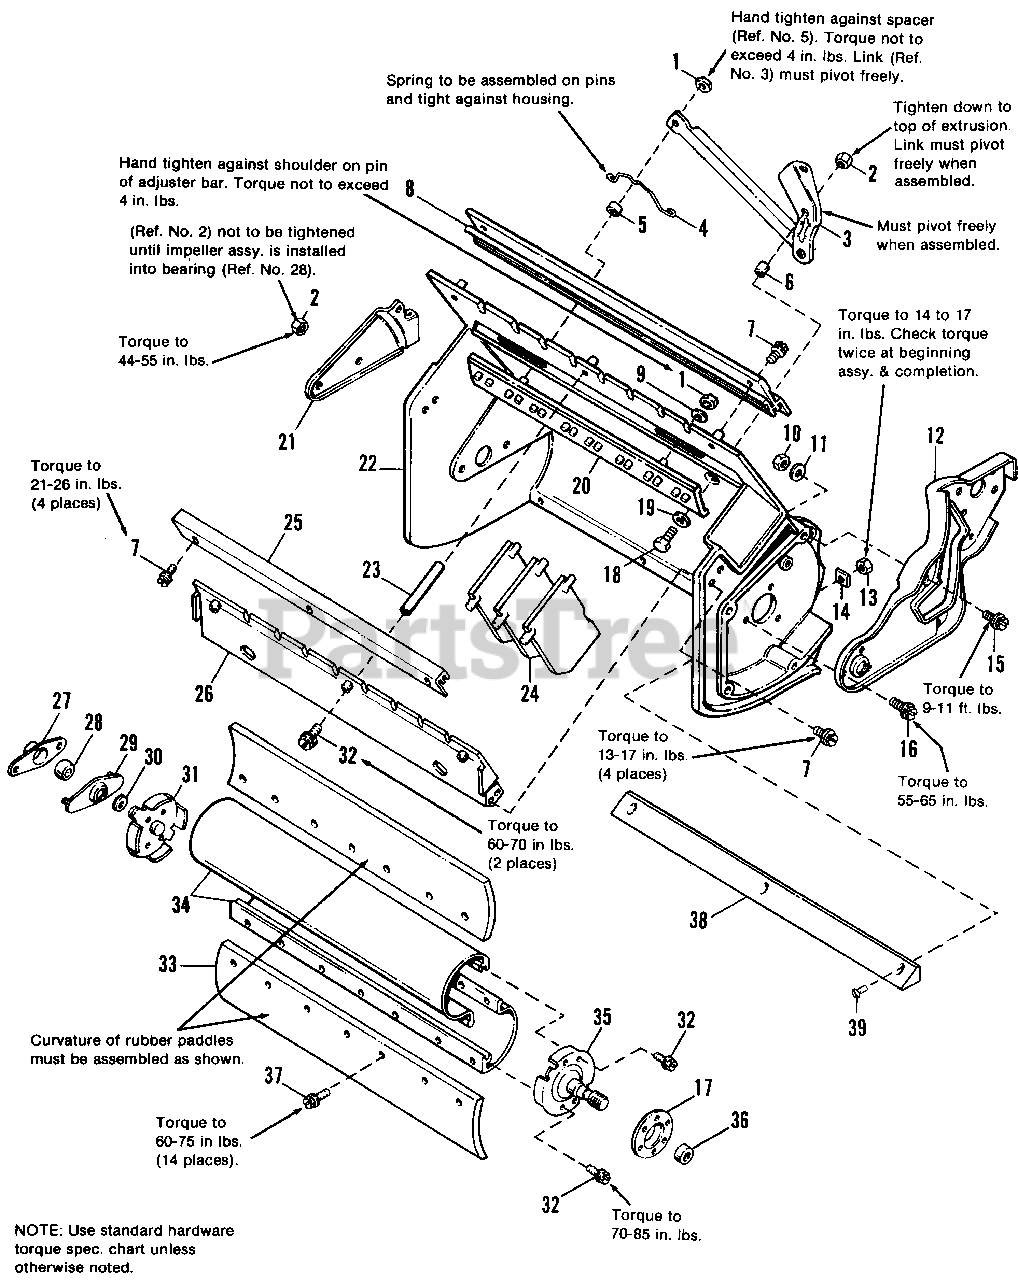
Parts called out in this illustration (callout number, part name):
1	NUT, Self-Threading
2	LOCKNUT, Hex, 1/4-20
3	VANE ASSY., Control
4	SPRING, Detent
7	SCREW, Hex, Wash. Hd., Slotted, #10-24 x 1/2
9	WASHER, Nylon
10	LOCKNUT, Hex, 5/16-18
11	WASHER, Plain, 5/16
13	NUT, Nylon Insert, #10-24
15	CAPSCREW, Hex Hd., 5/16-18 x 3/4
16	SCREW, Hex, Wash. Hd., #10-14 x 5/8
17	RETAINER, Bearing
18	CAPSCREW, Hex Hd., 1/4-20 x 1
19	WASHER, Plain, 1/4
20	BAR, Adjustment
21	BRACKET, R.H.
22	HOUSING, Impeller
26	MOUNT, Front
29	FLANGE ASSY.
30	WASHER, Plain, 5/8
31	FLANGE & SHAFT ASSY., R.H.
32	SCREW, Hex Wash. Hd., Slotted, #10-14 x 1
34	DRUM, Impeller
35	FLANGE & SHAFT ASSY., L.H.
37	SCREW, Hex Wash. Hd., Taptite, 1/4-20 x 1-1/4
38	SCRAPER BAR KIT
39	SCREW, Mach., Flat Hd., #10-24 x 1
